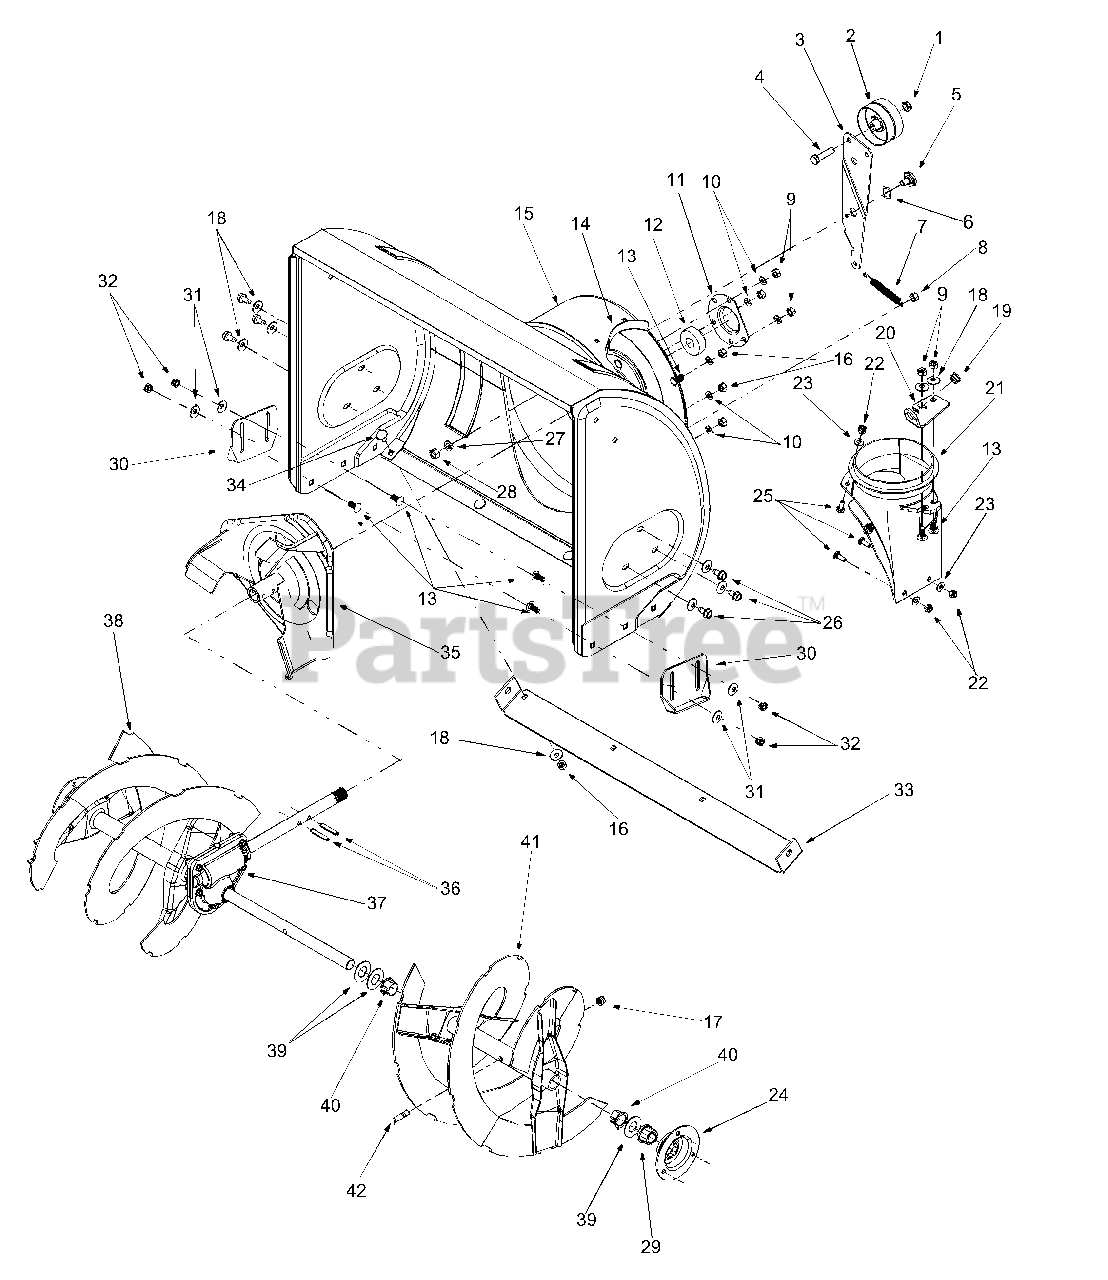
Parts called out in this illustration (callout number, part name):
1	Lock Jam Nut 3/8-24
2	Flat Idler
4	Hex Cap Screw 3/8-24 x 1.50
5	Shoulder Screw
6	Wave Washer
7	Extension Spring
8	Hex Nut 5/16-18
9	Hex Nut 5/16-18
10	Lock Washer 5/16
11	Housing
12	Ball Bearing
13	Carriage Bolt 5/16-18 x .75
17	Lock Nut 5/16-18
18	Bell Washer
19	Bushing
21	Chute Adapter
22	Hex Lock Nut 1/4-20
23	Flat Washer
25	Carriage Screw 1/4-20 x .75
26	Hex Washer Screw 5/16-18
27	Lock Washer 3/8
28	Hex Nut 3/8-16
29	Hex Flange Bearing
31	Bell Washer
32	Hex Nut 5/16-18
34	Carriage Bolt 5/16-18 x .62
37	30" Gear Assembly
40	Flange Bushing
42	Shear Bolt 5/16-18 x 1.5
